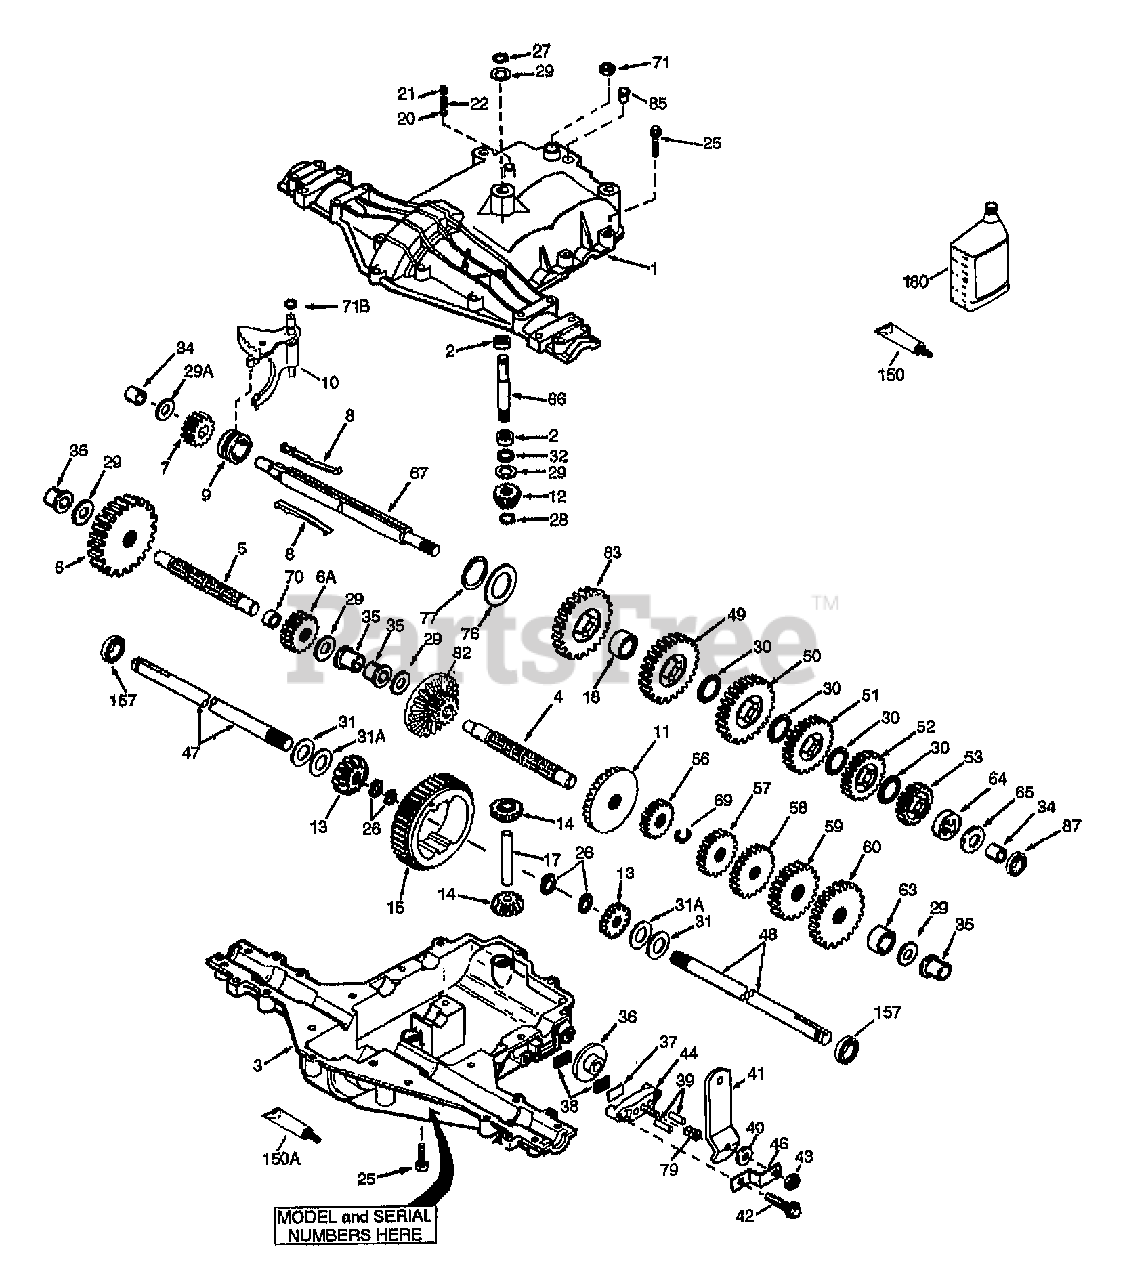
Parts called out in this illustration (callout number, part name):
2	NEEDLE BEARING
4	COUNTERSHAFT
5	OUTPUT SHAFT
6	SPUR GEAR
6A	SPUR GEAR
7	SPUR GEAR
8	SHIFT KEY
10	ROD & FORK
11	BEVEL GEAR
12	BEVEL GEAR
13	BEVEL GEAR
14	BEVEL GEAR
15	RING GEAR
17	DRIVE PIN
22	SPRING
26	RET RING
27	RET RING
28	RET RING
29	WASHER
30	WASHER
32	OIL SEAL
36	BRAKE DISK
37	BRAKE PAD PLATE
38	BRAKE PAD
39	DOWEL PIN
41	BRAKE LEVER
49	SPUR GEAR
50	SPUR GEAR
51	SPUR GEAR
52	SPUR GEAR
53	SPUR GEAR
56	SPUR GEAR
57	SPUR GEAR
58	SPUR GEAR
59	SPUR GEAR
60	SPUR GEAR
66	INPUT SHAFT
67	BRAKE SHAFT
69	RET RING
71	SQUARE CUT RING
82	BEV & SPUR GEAR
83	SPUR GEAR
87	OIL SEAL
150	LIQUID GASKET RTV SILICONE
150A	LIQUID GASKET LOCKTITE #242
157	OIL SEAL
180	OIL 80W90
